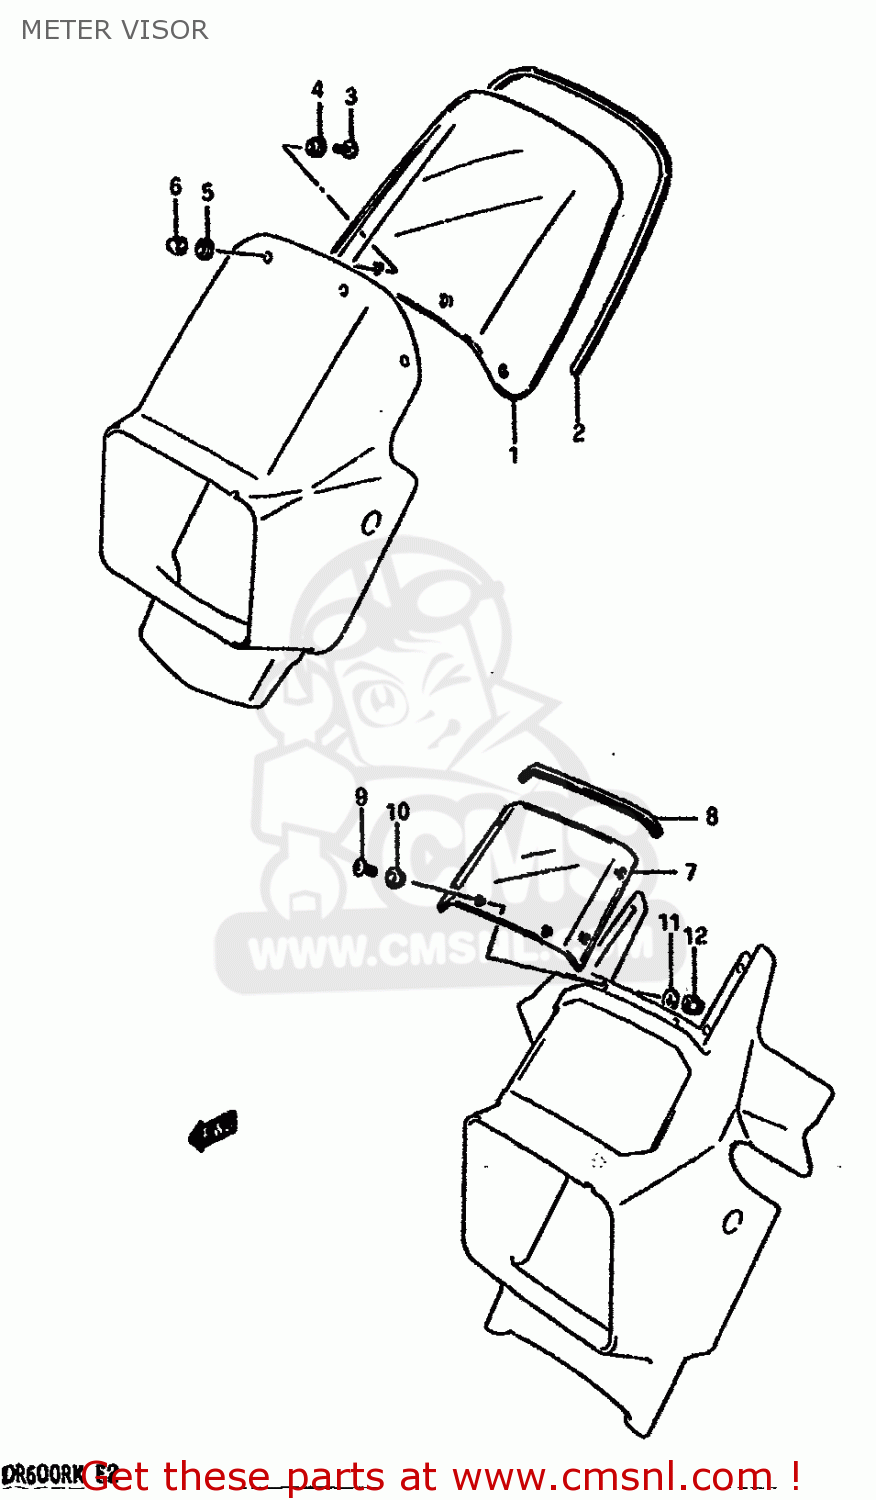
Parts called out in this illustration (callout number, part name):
1	VISOR, METER
2	MOLDING (L:545)
3	SCREW 5X10
4	CUSHION
5	WASHER,5MM
6	NUT
7	VISOR, METER
8	MOLDING
9	SCREW 5X10
10	CUSHION
11	WASHER,5MM
12	NUT
